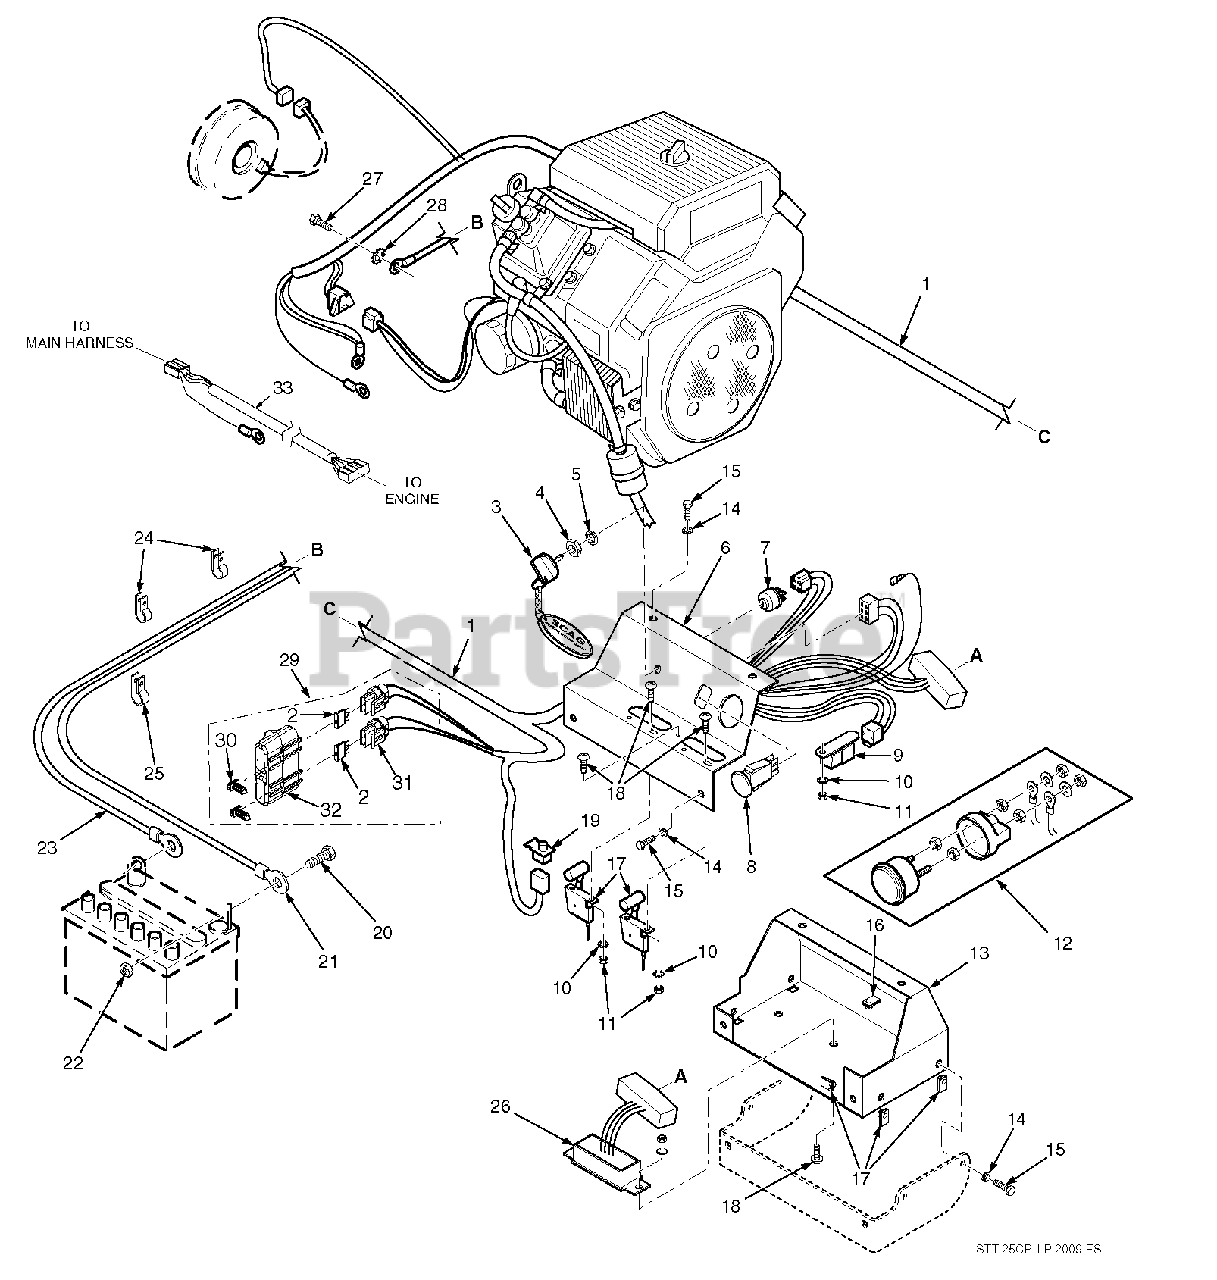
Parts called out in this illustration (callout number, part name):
1	Wire Harness, STT Air-Cooled
2	Fuse, 20 AMP
3	Key, Ignition
4	Nut, Hex 5/8-32
5	Lockwasher, 5/8" Internal
6	Instrument Panel, Top w/Decals
7	Key Switch
8	Switch, PTO
9	Relay
10	Lockwasher, #10 External Tooth
11	Nut, Hex #10-32
12	Ammeter
13	Base, Instrument Panel
14	Lockwasher, 1/4"
15	Bolt, Hex Head 1/4-20 x 3/4"
16	U-Nut, 1/4-20
17	Throttle And Choke Controls
18	Screw, Phillips Washer Head #10-32 x 1/2"
19	Switch, Interlock-Seat
20	Bolt, Hex Head 1/4-20 x 1/2"
21	Cable, Battery - Red
22	Nut, Hex 1/4-20
23	Cable, Battery - Black
24	Clamp, Cable 1/2" ID.
25	Clamp, Cable 3/4" ID.
26	Electronic Module
27	Bolt, Hex Head M8-1.25 x 20mm
28	Lockwasher, 5/16" External Tooth
29	Double Fuse Assembly, Sealed
30	Clip, Wire
31	Fuse Holder
32	Cover, Sealed Double
33	Wire Harness Adapter, Kohler
